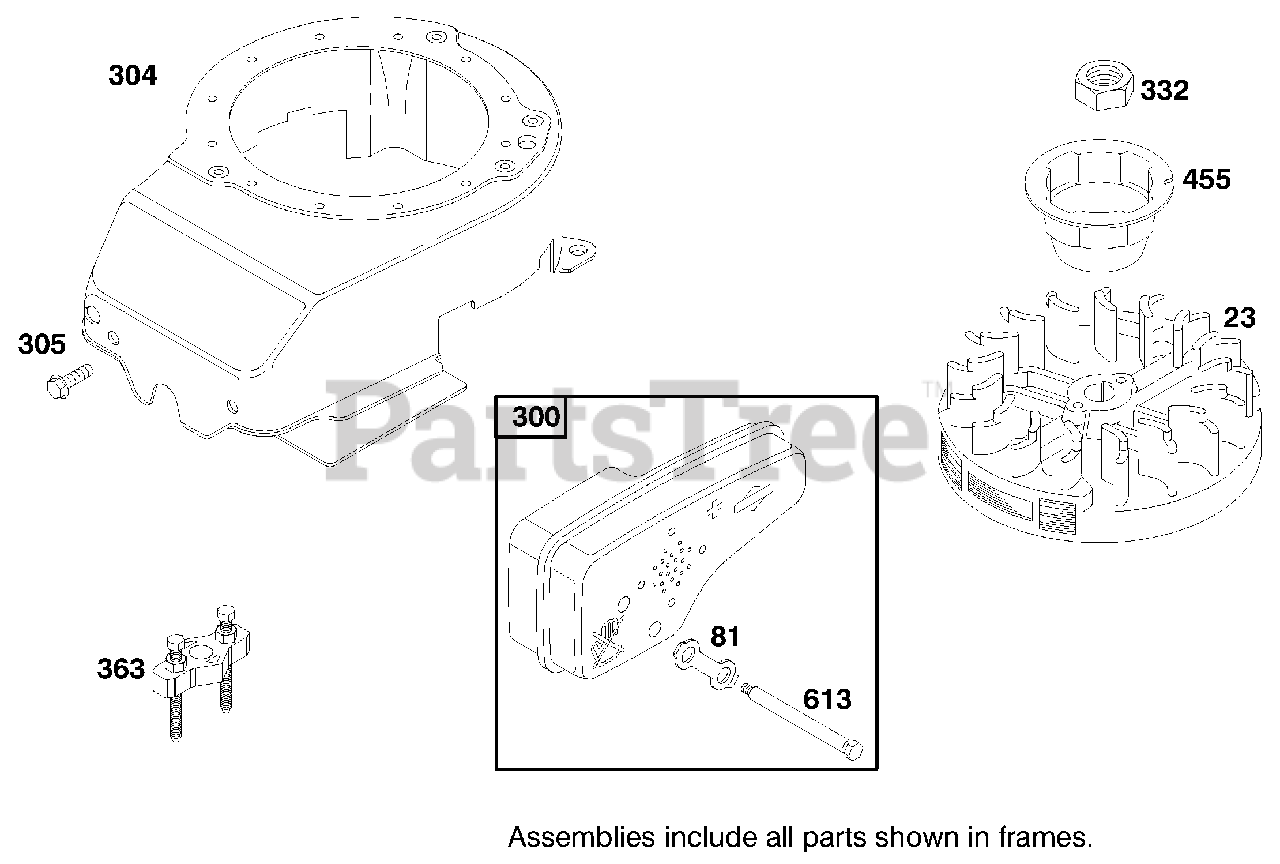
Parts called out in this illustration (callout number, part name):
23	Flywheel
81	Lock-Muffler Screw
300	Muffler-Exhaust
304	Housing-Blower
305	Screw-Hex
332	Nut-Flywheel
363	Flywheel Puller
455	Cup-Flywheel
613	Screw-Shoulder
